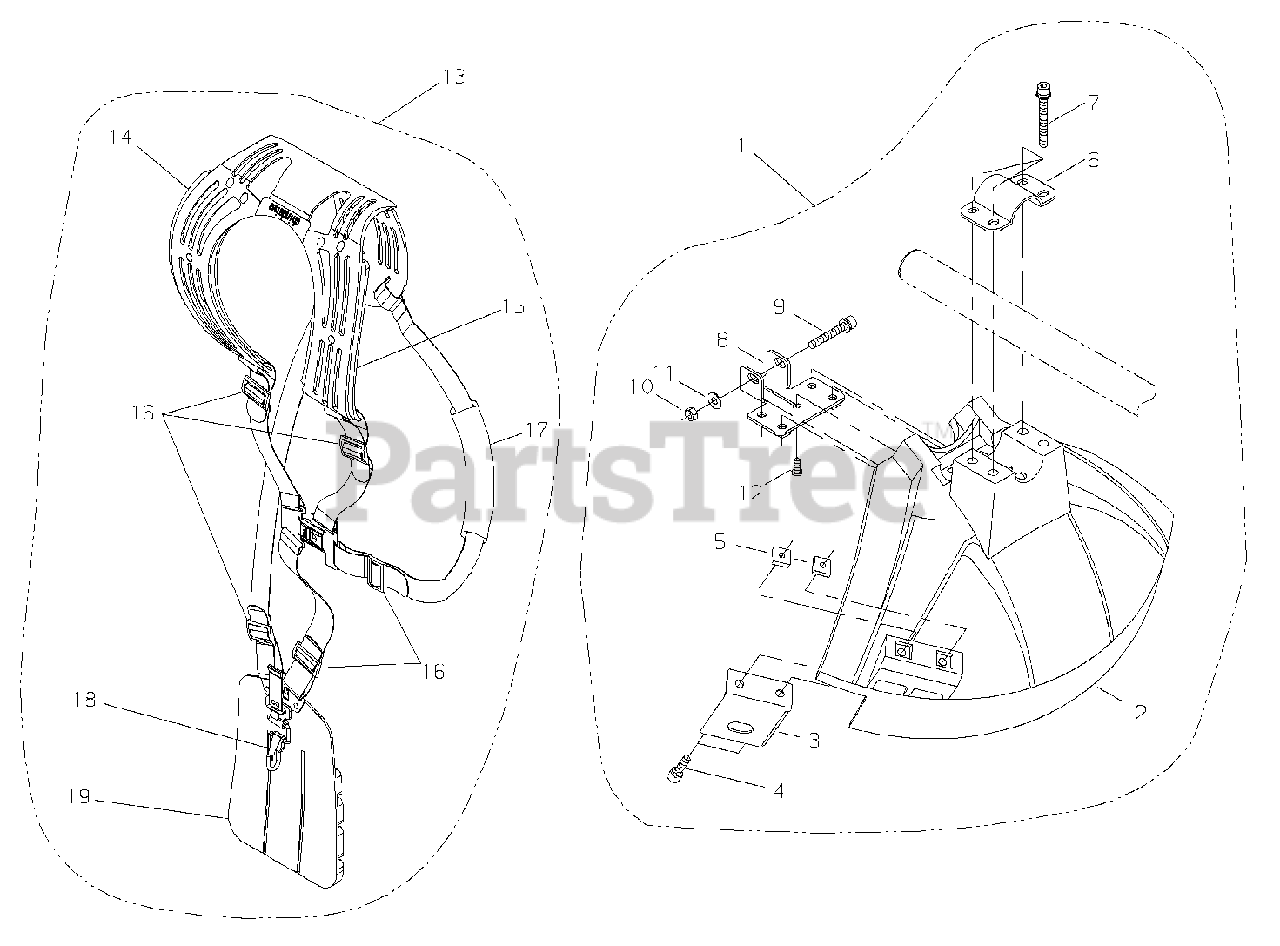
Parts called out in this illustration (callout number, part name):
1	GUARD ASSY
2	SHIELD, DEBRIS - BLACK
3	KNIFE, TRIMMER LINE
4	SCREW - 5X16
5	NUT - 5
6	CLAMP - UPPER
7	SCREW - 5X45
8	CLAMP - LOWER
9	SCREW - 6X40
10	NUT - 6
11	WASHER - 6
12	SCREW
13	HARNESS ASSY
14	PAD - RIGHT
15	PAD - LEFT
17	PAD
18	HOOK
19	PAD
